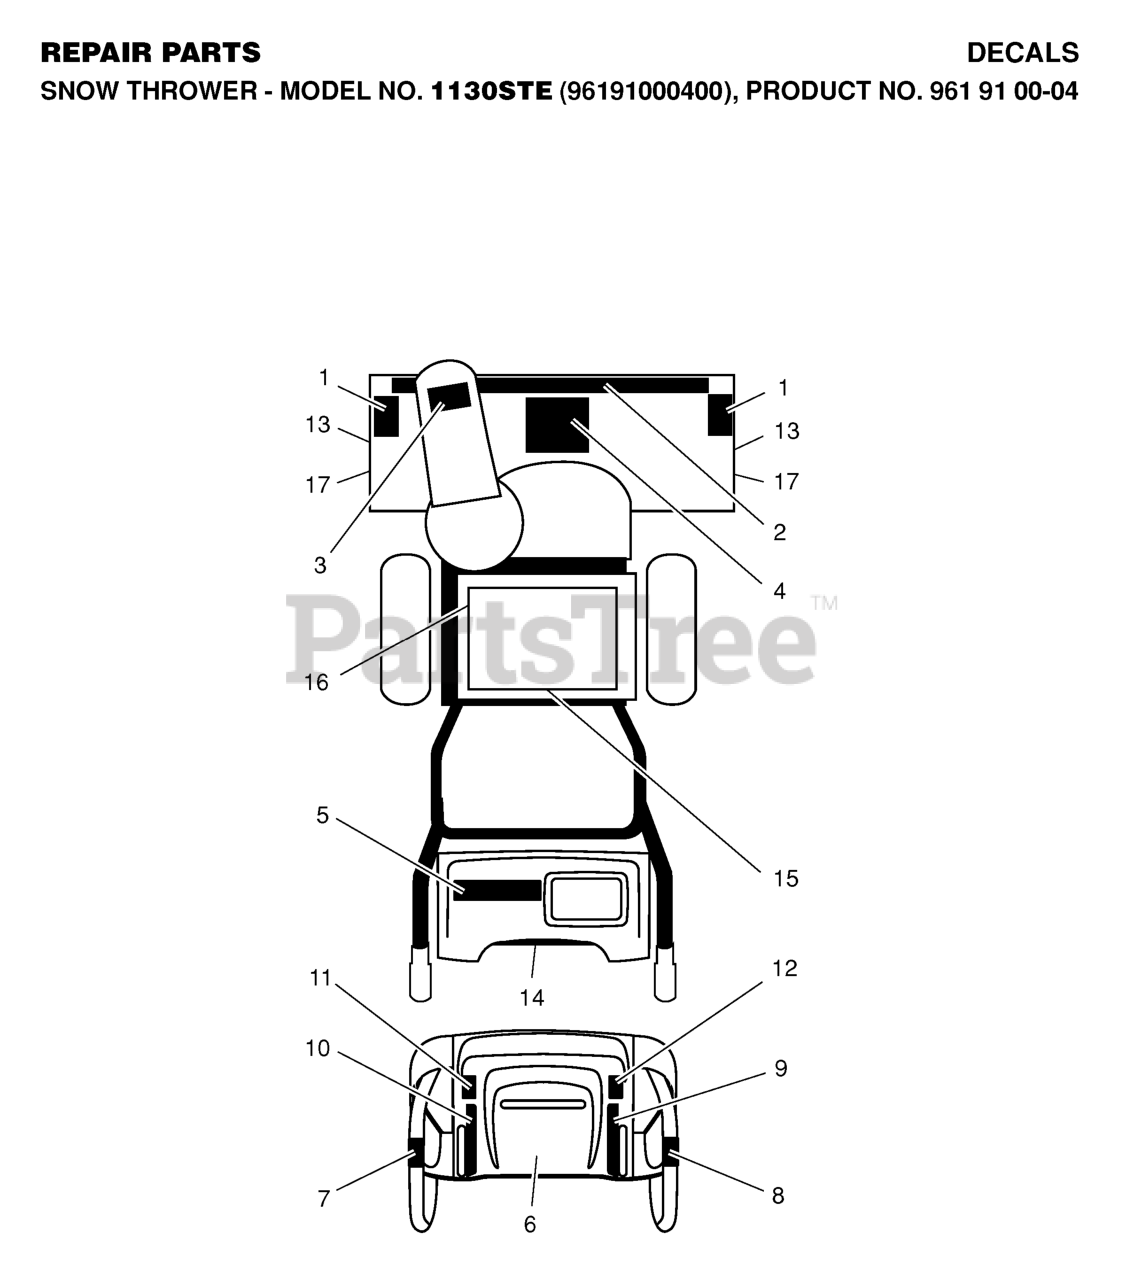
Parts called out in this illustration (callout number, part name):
1	DECAL.AUGER.SAFETY.
3	DECAL.CHUTE.SAFETY.
4	DECAL.AUGER."
6	DECAL.CONSOLE.INSTRUCTION
10	DECAL.REM.DEFLECTOR.LT
11	DECAL, LH TRIGGER
12	DECAL, RH TRIGGER
14	DECAL.FENDER
15	DECAL.BELT.GUARD.
17	DECAL, HUSQVARNA
